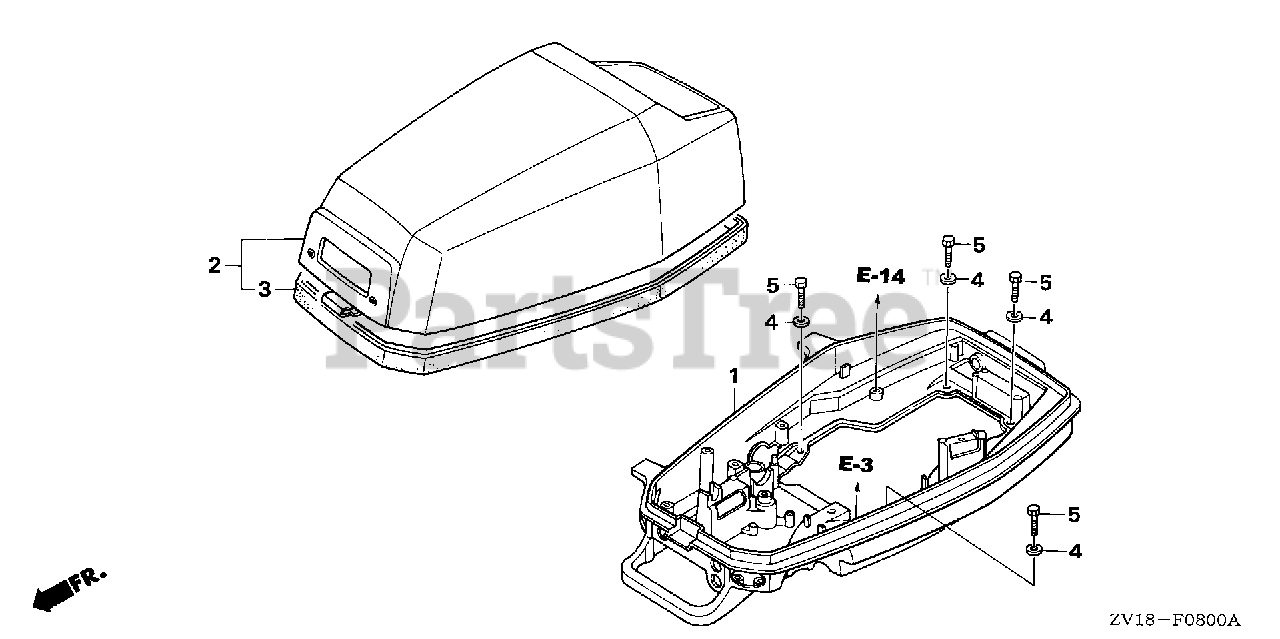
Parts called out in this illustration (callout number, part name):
1	CASE, ENGINE (LOWER) *NH282MU* (OYSTER SILVER METALLIC-U)
2	COVER, ENGINE *NH282MU* (OYSTER SILVER METALLIC-U)
3	SEAL, ENGINE COVER
4	WASHER, PLAIN (6MM)
5	BOLT, HEX. (6X16)
